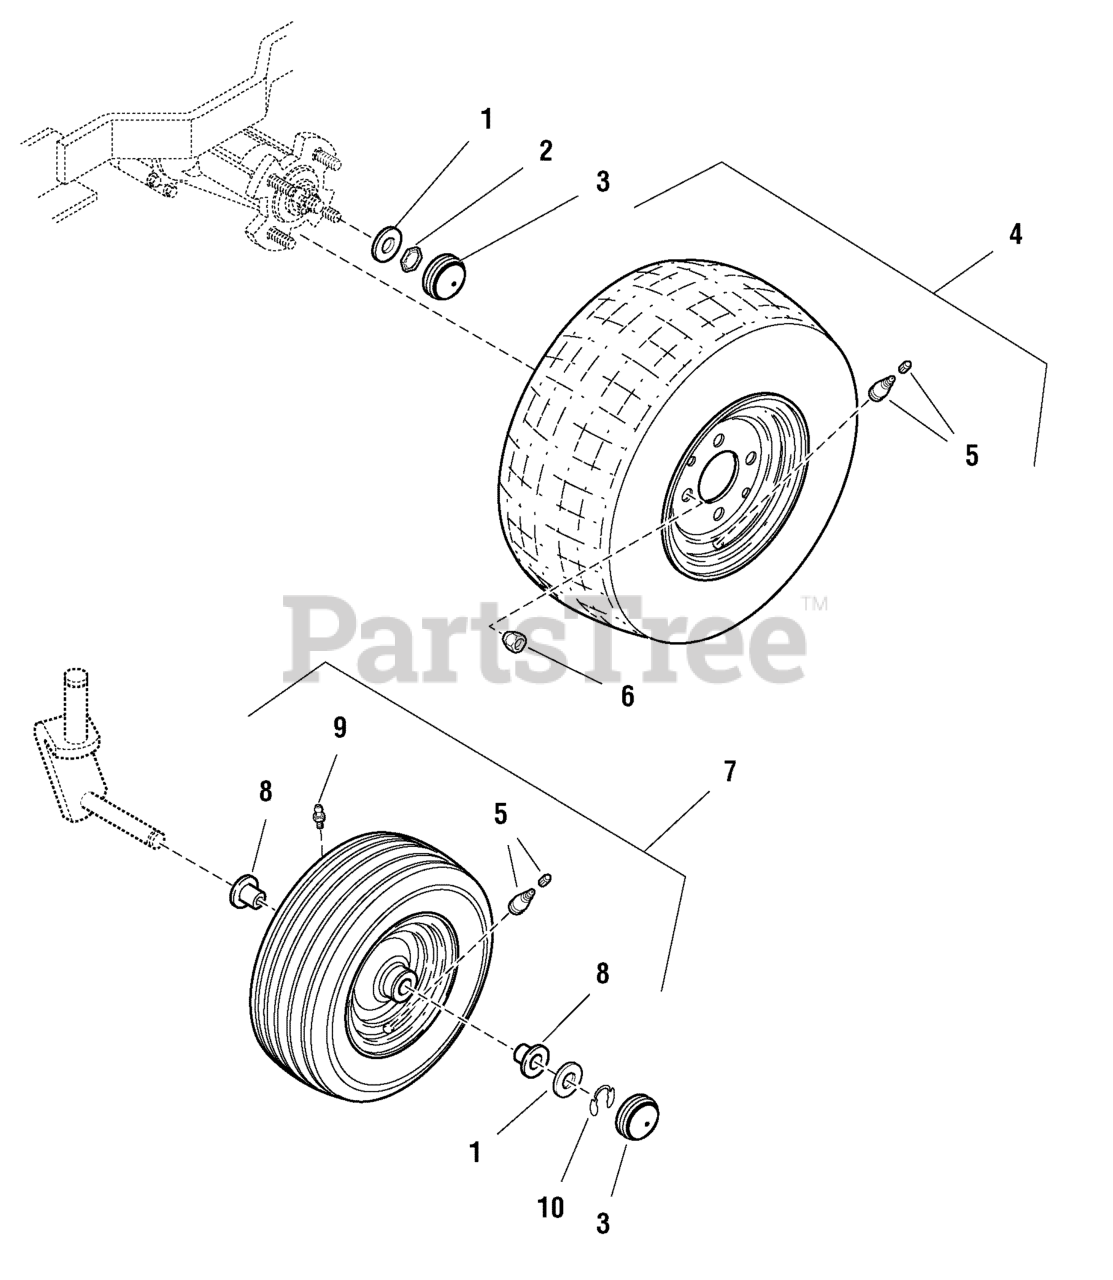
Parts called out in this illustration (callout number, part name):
1	WASHER, 3/4
2	NUT, Hex Lock PAL, 3/4-20
3	CAP, Hub
4	WHEEL & TIRE ASSEMBLY, Rear
5	VALVE STEM & CAP
6	NUT, Hex Lug, 7/16-20
7	WHEEL & TIRE ASEMBLY, Front
8	BUSHING, Wheel
9	FITTING, Lube
10	RING, Clipring for 3/4 Shaft
